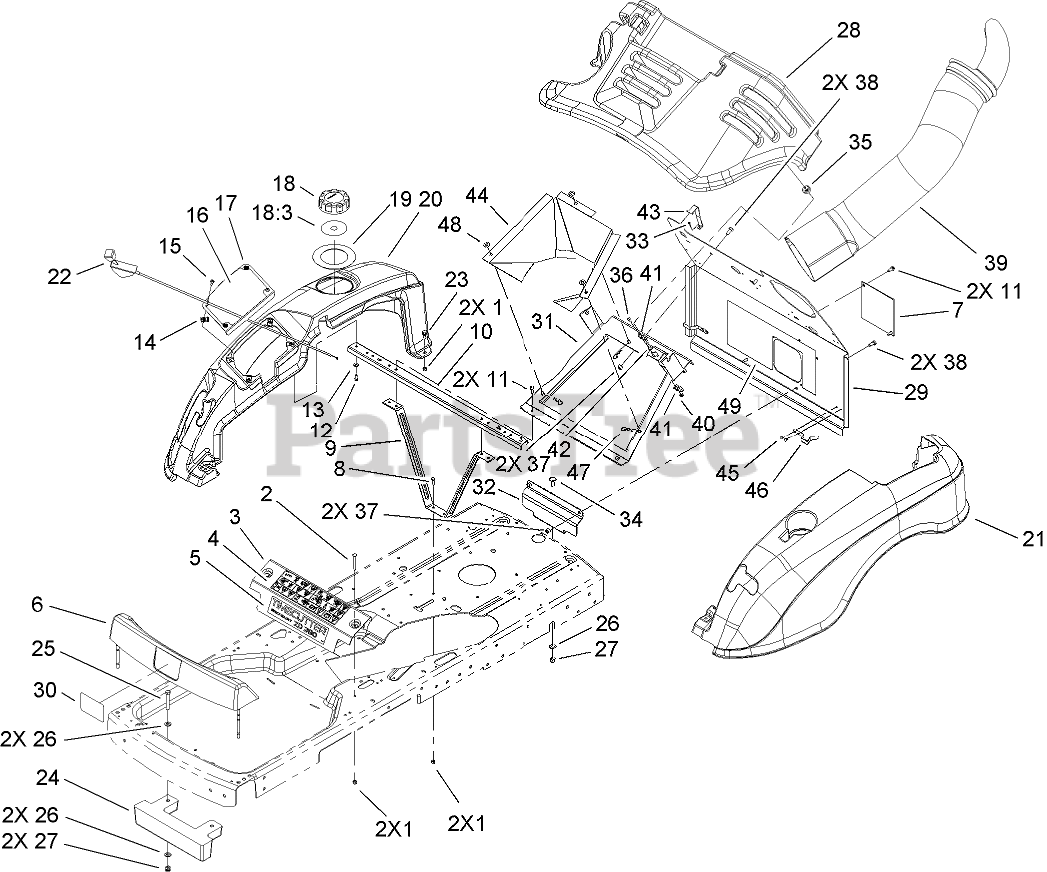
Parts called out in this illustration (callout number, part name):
1	NUT-LOCK, NI
2	SCREW-CARR
3	BRACKET-SUPPORT, FRONT
4	DECAL-DANGER
6	FOOTREST ASM
7	ACCESS DOOR ASM
8	SCREW-HH
9	BRACE ASM
10	CHANNEL-CROSS
11	SCREW-HWH, THREAD ROLL
12	SCREW-PLASTITE
13	WASHER-FLAT
15	SCREW-PRH
16	DECAL-CONTROL
17	PANEL-CONTROL
18	GAS CAP ASM
18:3	GASKET-CAP, GAS
19	SEAL-RUBBER
20	COVER-SIDE, RH
21	COVER-SIDE, LH
22	CABLE-THROTTLE
23	SCREW-SHOULDER
24	WEIGHT-BAGGER
25	SCREW-HH
26	WASHER-FLAT
27	NUT-LOCK, NI
28	COVER-ENGINE
29	SHIELD-HEAT, BAG
31	OFFSET HINGE ASM
32	HITCH-TRAILER
33	PIN-COTTER
34	SCREW-CARR
35	GROMMET
36	SCREW-HSBH
37	NUT-LOCK, NI
38	SCREW-HH
39	TUBE-DISCHARGE
40	NUT-LOCK, NI
42	PIN-HOOD
43	TAB-SWITCH
44	DUCT-FAN, ENGINE
45	SCREW-TAPTITE
46	CLIP-RETAINER, BAG
47	PIN-HAIR
48	WASHER-RUBBER
49	FOIL-HEAT SHIELD, BAG
